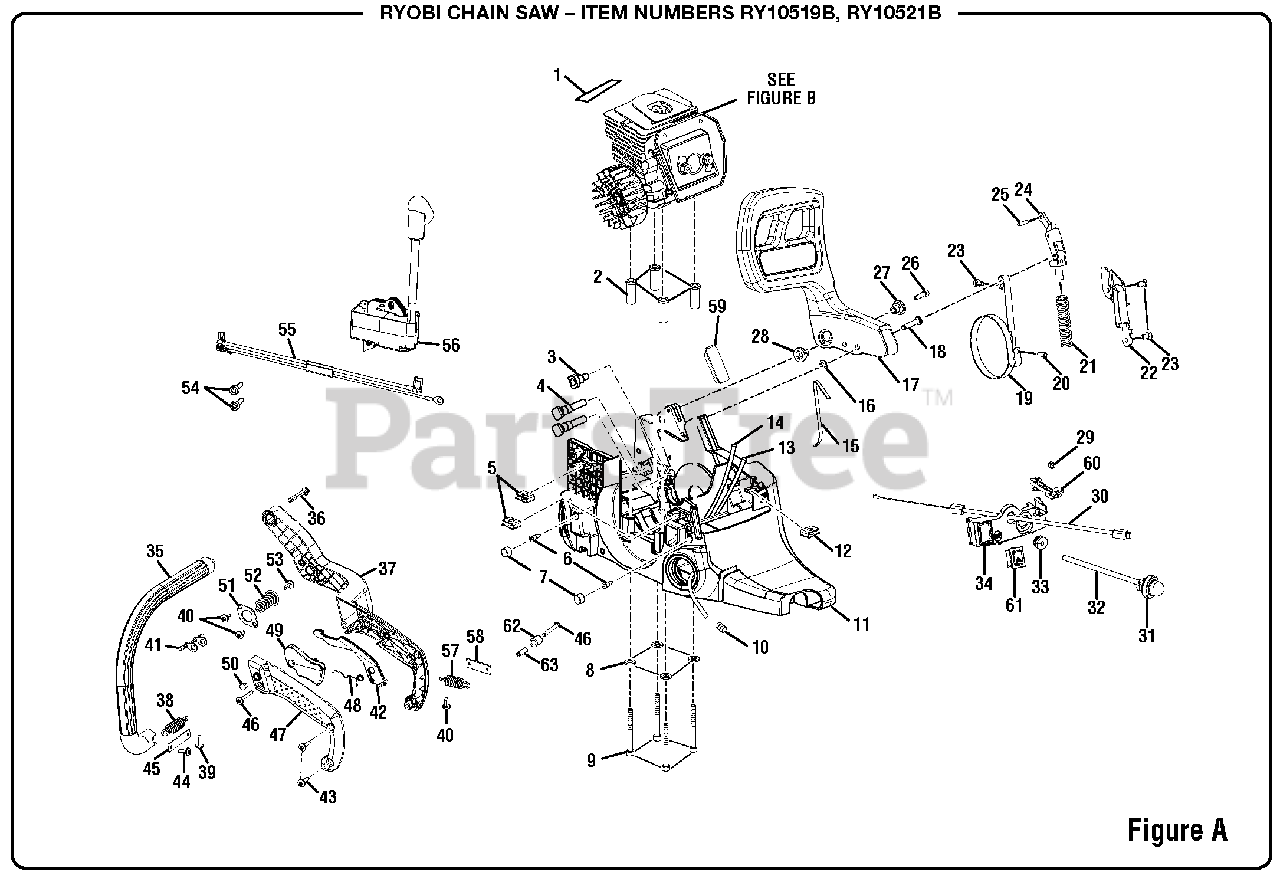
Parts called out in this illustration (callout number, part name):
1	Heat Reflector Tape
2	Spacer Insert
3	Oil Outlet Grommet
4	Guide Bar Bolt
5	Speed Nut ("U"-type)
6	Duck Bill Valve
9	Screw (10-24 x 2 in)
10	Hose Clamp
12	Speed Nut ("U"-type)
13	Inlet Tubing (166 mm)
14	Return Tubing (220 mm)
16	Retaining Ring
17	Hand Guard Assembly
18	Hand Guard Actuating Pin
19	Brake Band
20	Spring Pin
21	Spring
22	Chain Brake Cover
23	Screw (8-16 x 5/16 in)
24	Chain Brake Link Assembly
25	Spring Pin (Small)
26	Screw (8-32 x 5/8 in)
27	Pivot (Right Hand)
28	Pivot (Left Hand)
30	Throttle Cable
31	Primer Bulb
32	Rubber Tubing (64 mm)
33	Split Grommet
34	Control Panel
35	Front Handle
36	Screw (12-14 x 1-1/2 in)
37	Rear Handle
39	Screw (10-14 x 5/8 in, TF)
40	Screw (10-14 x 1/2 in, TF)
41	Limiter (Upper Isolator Spring)
42	Trigger Release
43	Screw (10-14 x 3/4 in, TF)
44	Screw (10-14 x 5/8 in, TF)
45	Spring Retainer
46	Screw (10-14 x 1-3/8 in)
47	Handle Cover
48	Torsion Spring
51	Isolator Plate
52	Isolator Spring
53	Screw (10-24 x 5/8 in, TF)
54	Screw (8-32 x 3/4 in, TF)
55	Ignition Switch Assembly
56	Ignition Kit
58	Spring Retainer
60	Choke Lever
61	Stop Switch
62	Rubber Bumper
63	Spacer (Spring Screw)
